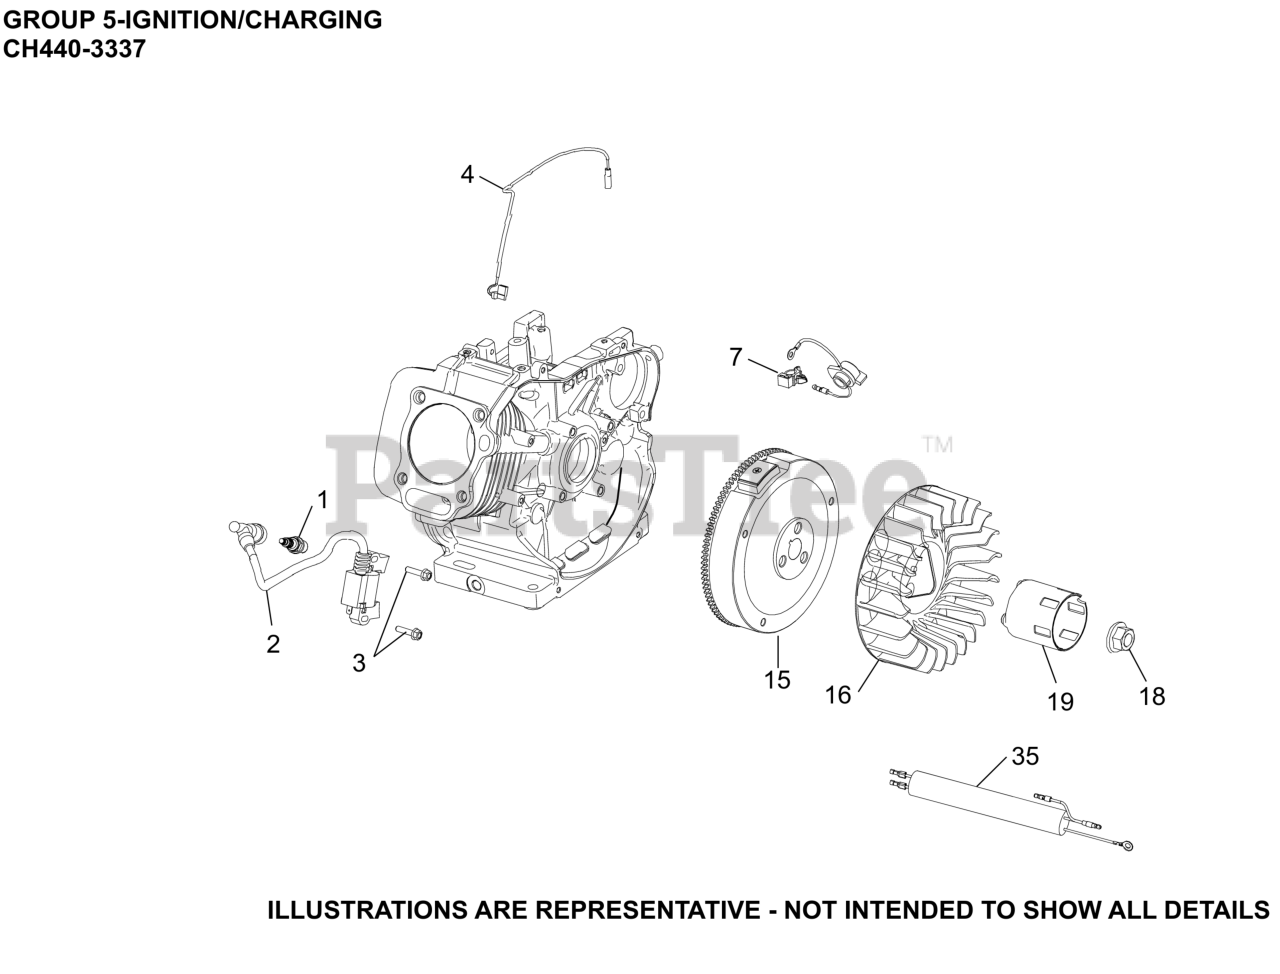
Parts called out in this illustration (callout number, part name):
1	SPARK PLUG
2	MODULE, IGNITION
3	SCREW, M6 X 25-(#25086436S)
4	LEAD, GROUND TO KILL
7	CLIP, WIRE HARNESS
15	FLYWHEEL, ASSEMBLY CAST IRON
16	FAN, FLYWHEEL
18	NUT, FLYWHEEL
19	CUP, STARTER DRIVE
35	LEAD, MICROSWITCH
